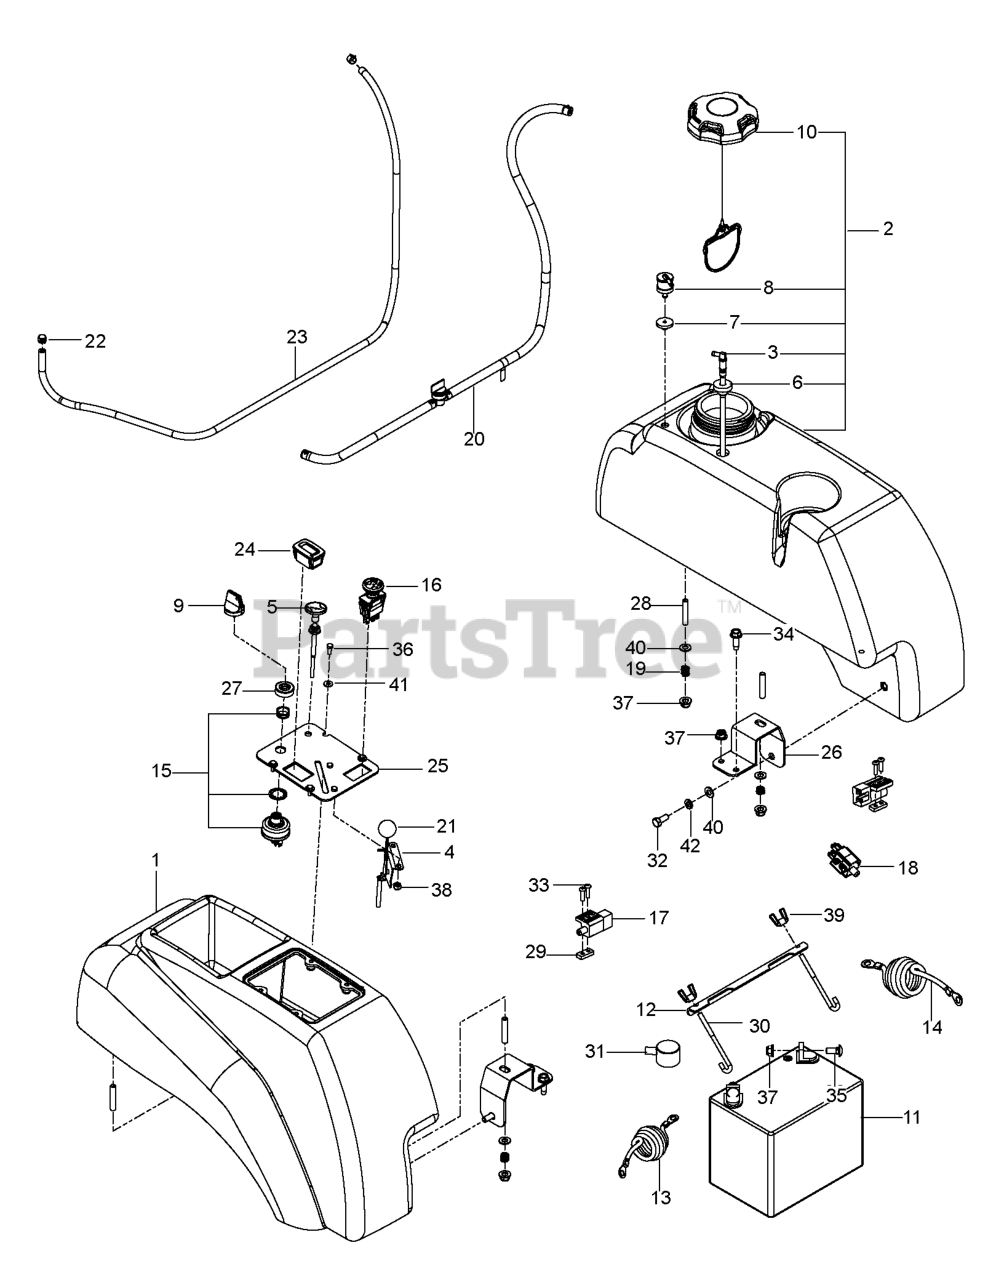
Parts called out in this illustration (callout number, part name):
1	FENDER CONSOLE
2	FUEL.TANK.ASSY.LH.MZ.GRY
3	FITTING, FUEL
4	THROTTLE CABLE
5	CABLE, CHOKE, 38
6	RUBBER GROMMET
7	GROMMET, CHECK VALVE
8	VALVE.FUEL.CHECK
9	KEY, IGNITION
10	CAP, FUEL
11	BATTERY, 12 V 330 AMP
12	BRACKET, BATTERY MOUNT
13	CABLE.BATT.SOLENOID.MZ.RED.25"
14	CABLE.GROUND.BATT.MZ.BLACK.39"
15	SWITCH, IGNITION, INDAK
16	RP SWITCH.PTO.TERMINAL.STD.RED
17	SWITCH INTERLOCKT
18	SWITCH.INTRLCK.CLUTCH.
20	FUEL.HOSE.SHUT.OFF.ASM.10".26"
21	KNOB.ROUND.BALL.BLACK
22	CLAMP, HOSE
23	HOSE.3/16".VAPOR.LINE.64"LGTH
24	GUAGE.SRVCMNDR.HRMTR.
25	PLATE, CONSOLE, BLK
26	SUPPORT, TANK, BLK
27	CAP IGNITION NUT
28	STUD, 5/16C
29	PLATE NUT ZTR
30	HOOK, "J"
31	COVER.TERMINAL.BATTERY
32	BOLT.FIN.HEX.5/16-18X3/4
33	SCR #10-24 X .75 SKT HD BLK
34	HCS #10-24 X 1/2
35	RP BOLT 5/16-18 X3/4 ZN/YEL GR
36	SCREW
37	5/16-18 NYLOC FLANGE NUT
38	NUT 10-24 NYLOC
39	WING NUT 1/4
40	WASHER
42	WASH.5/16.SLW.ZD
